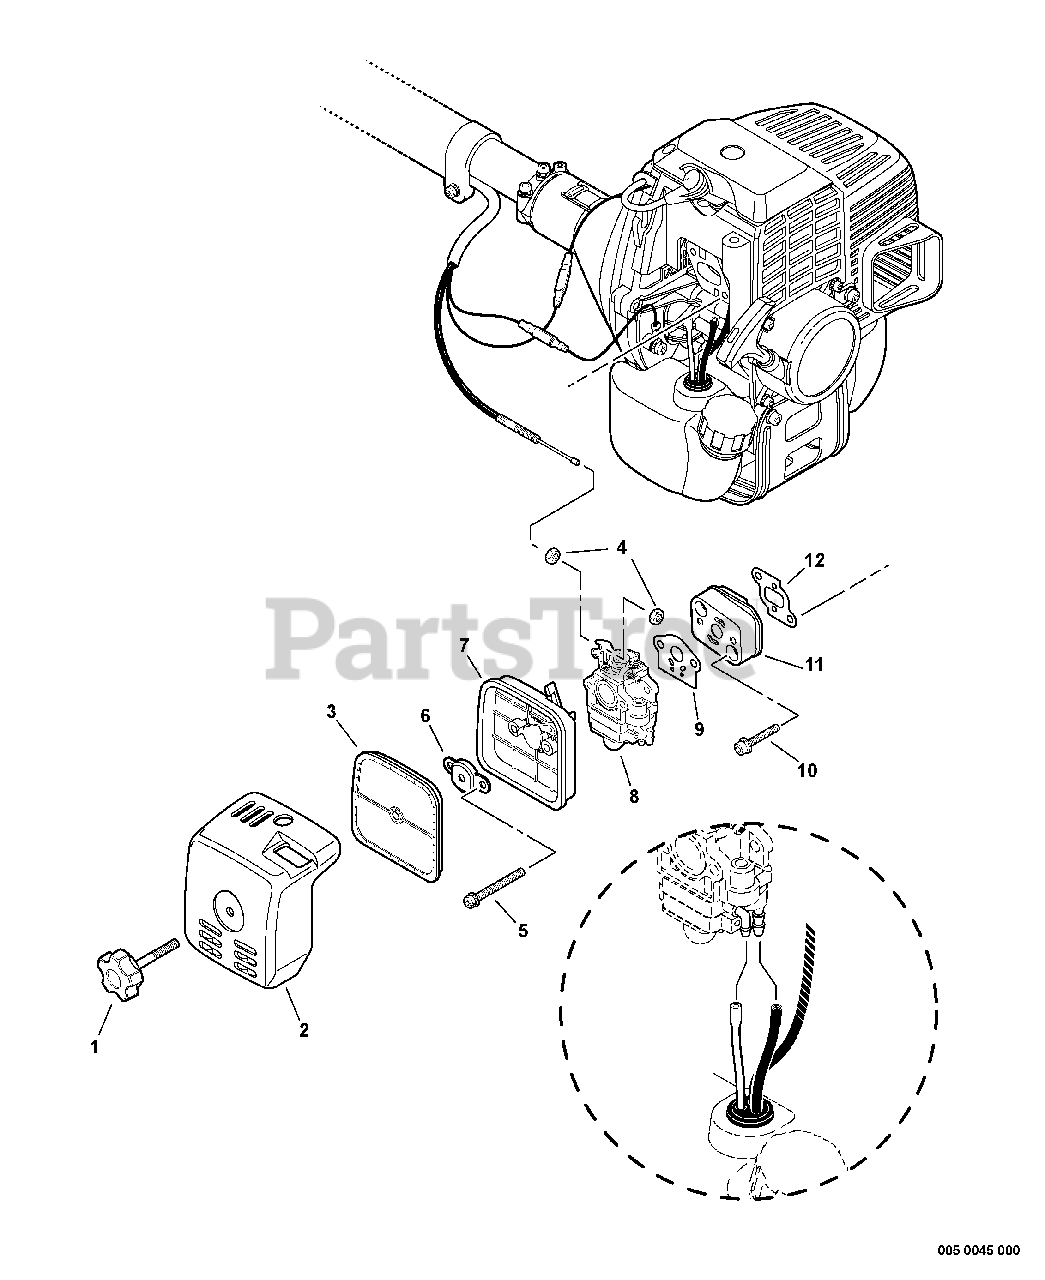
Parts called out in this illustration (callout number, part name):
1	THUMBSCREW
2	COVER, AIR FILTER
3	FILTER, HEAVY-DUTY AIR
5	SCREW 5×60
6	PLATE, PREVENT
7	CASE, AIR FILTER
8	CARBURETOR
9	GASKET, CARBURETOR
10	BOLT 5×25
11	INSULATOR
12	GASKET, INTAKE
